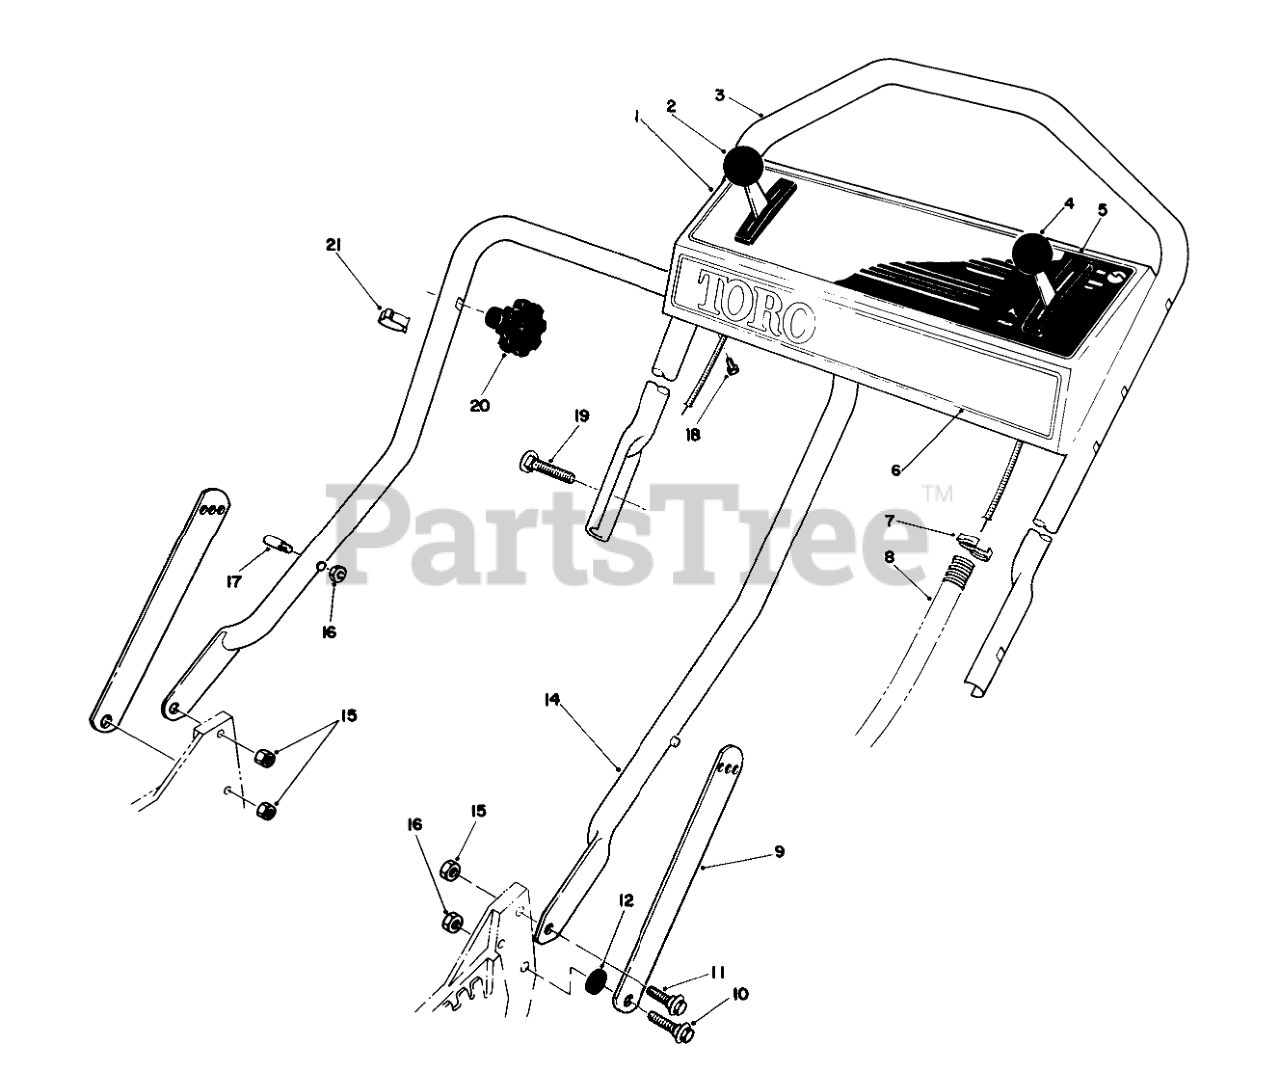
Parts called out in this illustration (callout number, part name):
1	Panel-Control (Incl. Ref. #5)
2	GROUND SPEED CONTROL
3	Handle-Upper
4	THROTTLE CONT-SERVICE
5	Decal-Instruction Panel
6	Decal-Toro
7	FITTING-RING
8	CONTROL CABLE COVER
9	Handle Latch
10	SCREW-SHOULDER
11	SCREW-SHOULDER
12	SPACER
14	LOWER HANDLE ASM
15	NUT-LOCK, NI
16	NUT-LOCK, NI
17	HANDLE PIN
18	SCREW-HWHTF
19	5/16-18 X 2 HNDLE SCREW
21	BOWDEN CLIP
